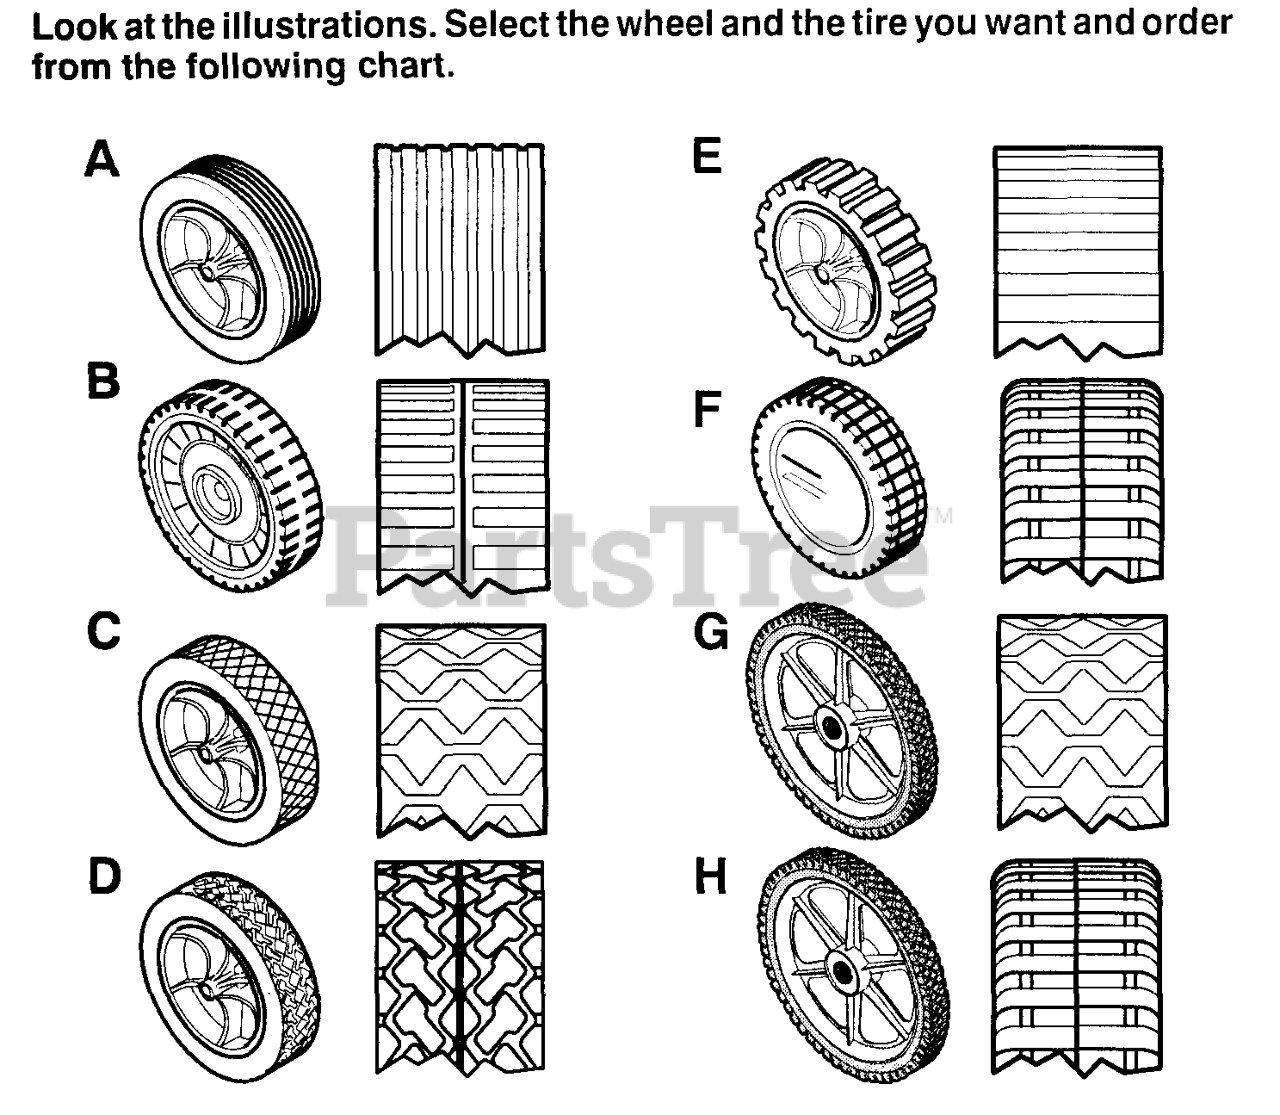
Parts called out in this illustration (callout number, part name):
A	WHEEL & TIRE ASSEMBLY, Light Gray, 8"
A	8-inch Plastic, Dark Gray
A	8-inch Metal, White
B	7-inch Plastic, White
B	7-inch Plastic, Light Gray
B	7-inch Plastic, Dark Gray
C	6-inch Plastic, White
C	7-inch Plastic, White
C	7-inch Plastic, Light Gray
C	7-inch Plastic, Dark Gray
C	8-inch Plastic, White
C	8-inch Plastic, Light Gray
C	8-inch Plastic, Dark Gray
C	8-inch Metal, White
D	7-inch Plastic, White
D	WHEEL & TIRE ASSEMBLY, White, 8"
D	8-inch Plastic, Light Gray
D	8-inch Plastic, Dark Gray
E	WHEEL & TIRE ASSEMBLY, White, 8"
E	8-inch Plastic, Dark Gray
E	8-inch Metal, White
F	WHEEL & TIRE ASSEMBLY, White, 8"
F	8-inch Plastic, Light Gray
F	8-inch Plastic, Dark Gray
F	8-inch Ball Bearing, Light Gray
F	8-inch Ball Bearing, Dark Gray
G	14-inch, White
G	14-inch, Light Gray
G	14-inch, Dark Gray
G	WHEEL & TIRE ASSEMBLY, White, 14"
G	14-in, Ball Bearing, Light Gray
G	14-in, Ball Bearing, Dark Gray
H	14-inch, White
H	14-inch, Light Gray
H	14-inch, Dark Gray
H	WHEEL & TIRE ASSEMBLY, Ball Bearing, 14"
H	14-in, Ball Bearing, Light Gray
H	14-in, Ball Bearing, Dark Gray
